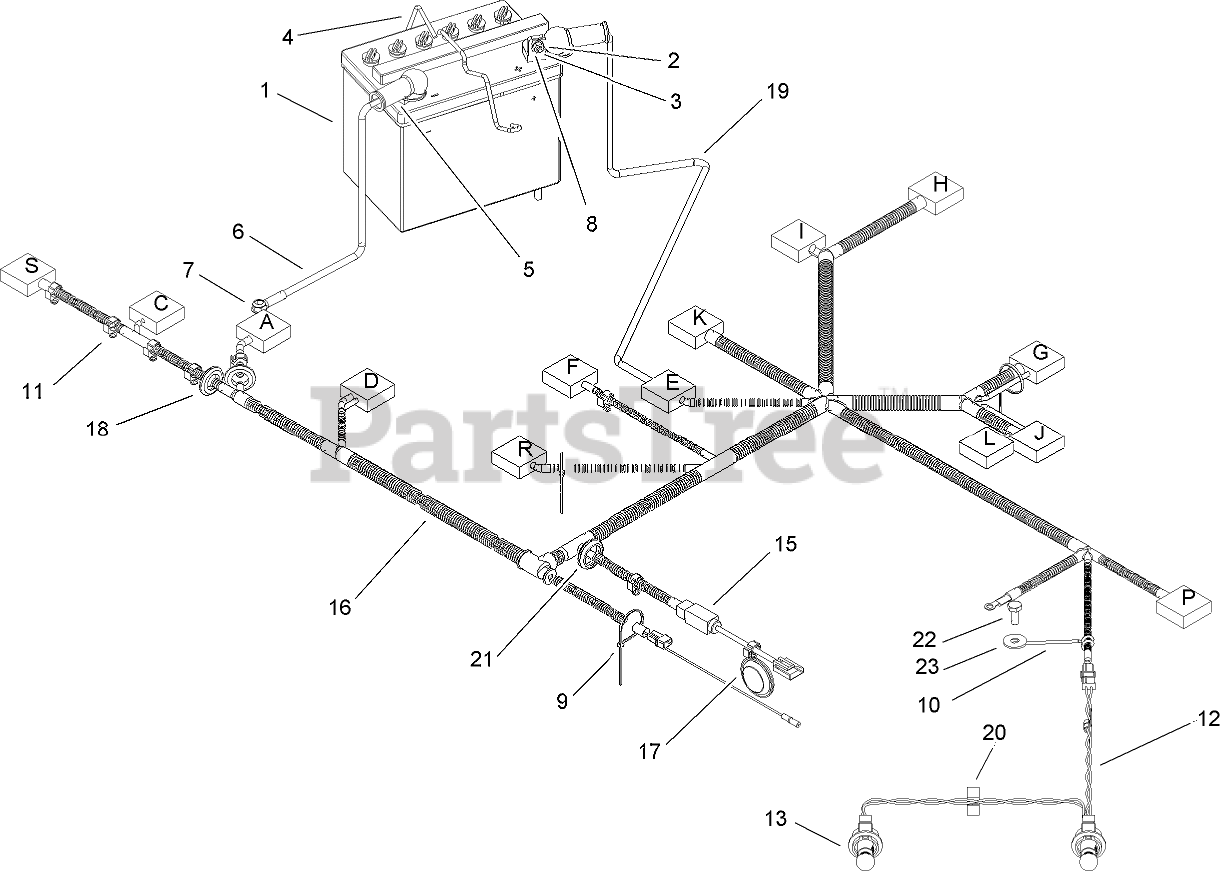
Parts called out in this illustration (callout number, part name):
1	BATTERY
2	NUT-HEX
3	SCREW-HH
4	CLAMP-BATTERY
5	BOOT-RUBBER
6	CABLE-BATTERY, NEGATIVE
7	NUT-LOCK, NI
8	WASHER-FLAT
9	TIE-CABLE
10	HOLDER-HARNESS, WIRING
11	CLIP-SNAP
12	HARNESS-WIRE, LIGHT
13	BULB-LIGHT
15	HARNESS-CLUTCH
16	HARNESS-WIRING
18	BUSHING
19	CABLE-BATTERY, POSITIVE
20	CLIP-NYLON
21	BUSHING
22	SCREW-HH
23	WASHER-PLAIN
